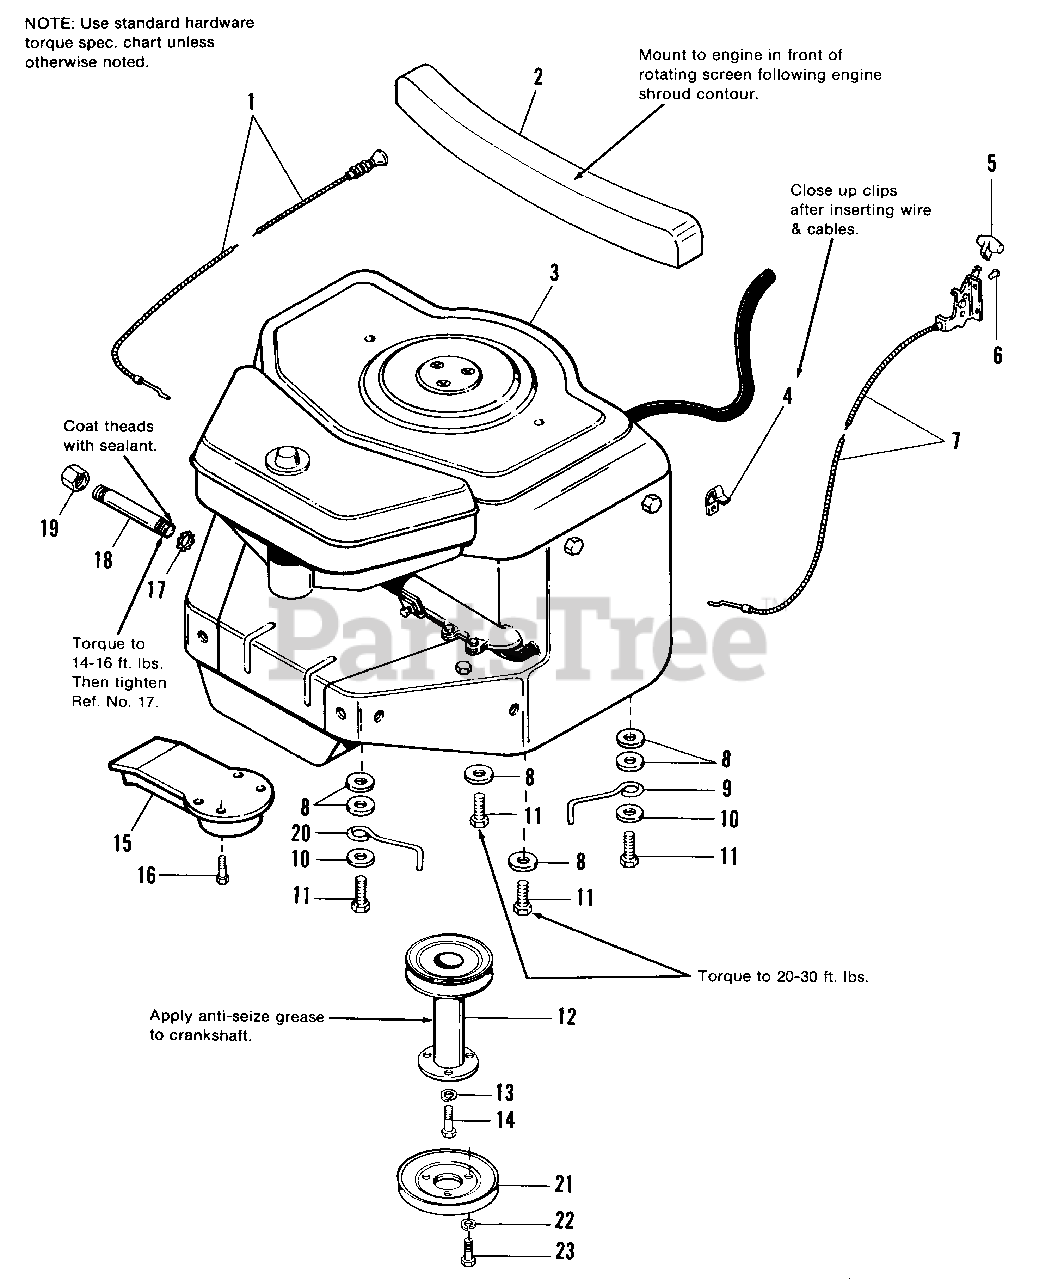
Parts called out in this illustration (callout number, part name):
1	CONTROL, Choke
2	BAFFLE, Engine, Rear
3	ENGINE, 16 H.P. Briggs & Stratton
4	CLIP, Wire
6	RIVET, Pop, 1/4 x 7/16
7	CONTROL ASSY.
8	WASHER, Plain
10	WASHER, Plain, 3/8
11	SCREW, Taptite, 3/8-16 x 1-3/4
12	PULLEY ASSY., Engine
13	LOCKWASHER, 7/16
14	CAPSCREW, Hex, 7/16-20 x 1-1/4
15	EXTENSION ASSY., Muffler
16	SCREW, Hex Thd., Cutting, #8-32 x 3/8
17	LOCKNUT, Conduit, 3/8 (BC-38)
18	PIPE, Oil Drain
19	PIPE, Cap, Hex
22	LOCKWASHER, 5/16
23	CAPSCREW, 5/16-18 x 1-1/2
